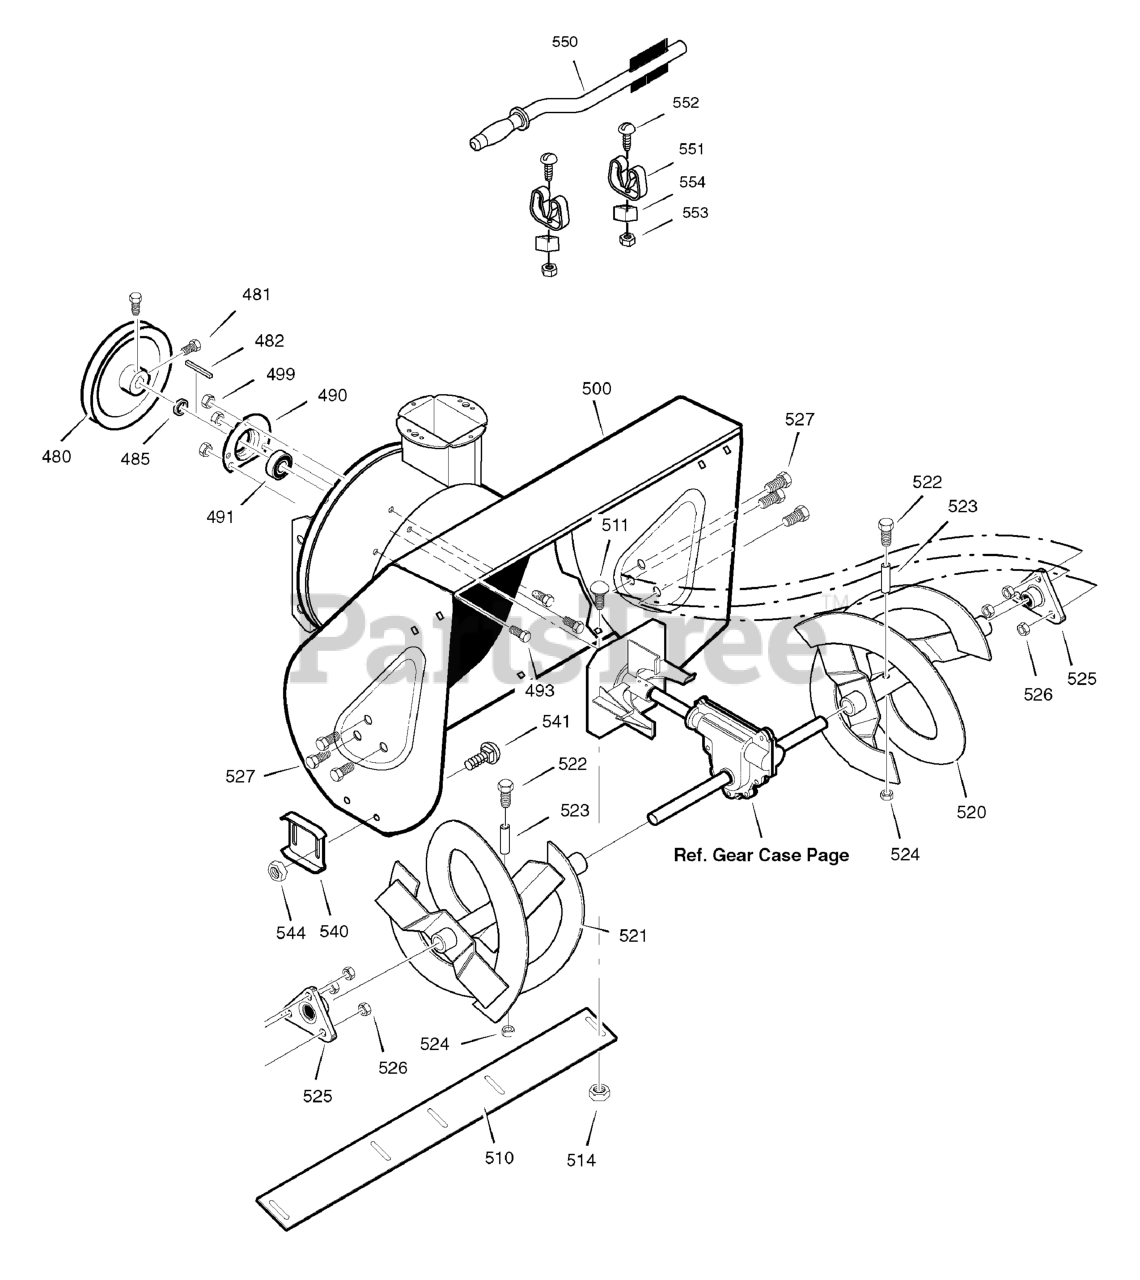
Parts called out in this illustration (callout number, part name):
480	PULLEY, 4L 6-1/8 x .67
481	SCREW, 5/16-18 x 5/8
482	KEY, Square, 3/16 x 3/4
485	SPACER, Friction Pulley
490	RETAINER, Ball Bearing
491	BEARING, Ball
493	BOLT, 5/16 - 18 x 3/4
499	NUT, Hex Whiz Lock Flange 5/16-18
500	HOUSING ASSEMBLY
510	BLADE, Scraper
511	BOLT, 1/4 - 20 x 5/8
514	NUT, 1/4 - 20
520	AUGER ASSEMBLY, L.H.
521	AUGER ASSEMBLY, R.H.
522	SCREW, 1/4 - 20 x 1-3/4
523	SPACER, Sleeve
524	NUT, 1/4 - 20
525	BEARING, Flange
526	NUT, 5/16 - 18
527	SCREW, 5/16-18 x 3/4
540	SKID, Height Adjust
541	BOLT, 5/16 - 18 x 1/2
544	NUT, 5/16 - 18
550	BRUSH, Cleanout
551	CLIP, Retainer
552	SCREW
553	NUT
554	BLOCK
